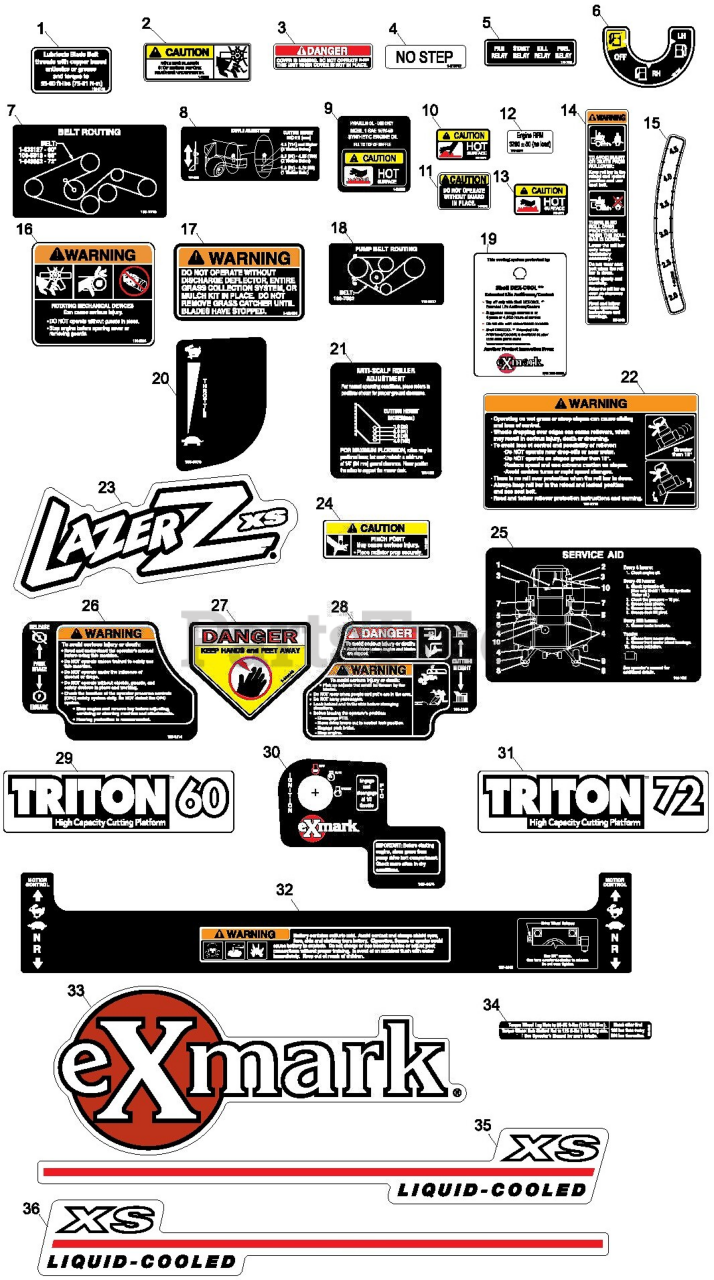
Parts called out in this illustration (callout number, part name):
1	DECAL,BOLT TORQUE
2	DECAL-FAN, RADIATOR
3	DECAL-COVER, MISSING
4	DECAL,NO STEP
5	DECAL,RELAY
6	DECAL-VALVE, FUEL
7	DECAL,BELT ROUTING
8	DECAL,BAFFLE ADJUSTMENT
10	DECAL-CAUTION
11	DECAL-GUARD
13	DECAL-CAUTION
14	DECAL-WARNING, FOLDING RO
15	DECAL-HEIGHT, DECK
16	DECAL,WARNING
17	DECAL-WARNING, DISCHARGE
18	DECAL,HYDRO BELT ROUTING
19	DECAL,SHELL COOLANT
21	DECAL,ANTISCALP
22	DECAL-WARNING
23	DECAL,LAZER XS MODEL
24	DECAL,RADIATOR ASSEMBLY
25	DECAL,SERVICE AID
26	DECAL,PARK BRAKE
27	DECAL-DANGER
28	DECAL,DECK HEIGHT
29	DECAL,TRITON 60
30	DECAL,IGNITION/PTO
31	DECAL,TRITON 72
32	DECAL-CONSOLE, TOP
33	DECAL,EXMARK
35	DECAL,HOOD LXS LC LH
36	DECAL HOOD LXS LC RH
